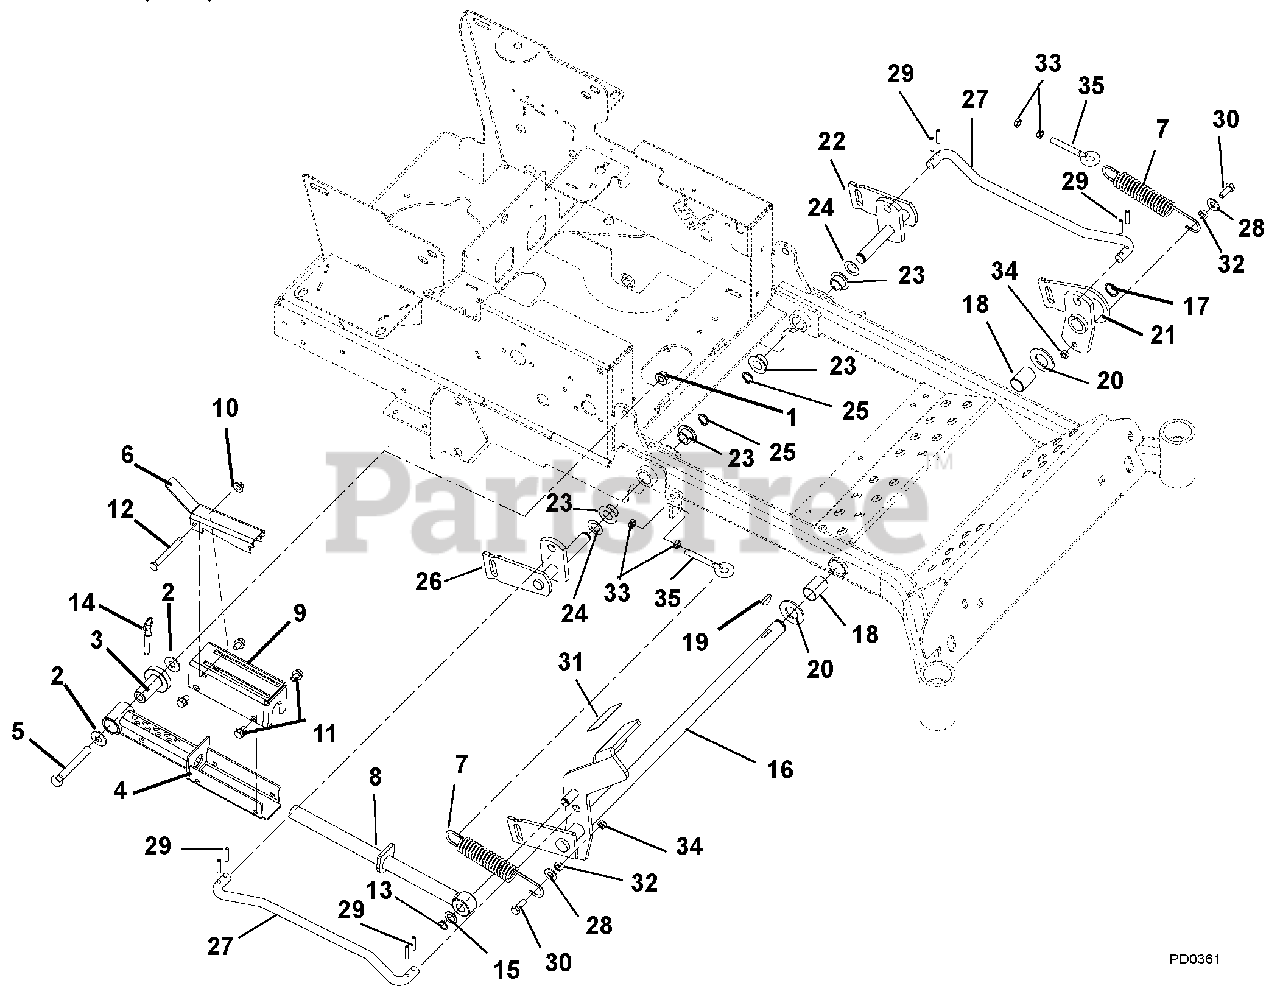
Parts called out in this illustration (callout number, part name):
1	Nut, Locking Top Flange .50-13
2	Washer, Flat Steel .531 x 1.25 x .10
3	Bearing, Pedestal
4	Weldment, Mechanical Lift
5	Bolt, Hex .50-13 x 3.75 Grade 5
6	Lock-Up, Mechanical Lift
7	Spring, Tension .162 x 1.25 x 8.25 Weldment 25
8	Weldment, Mechanical Lift Shaft
9	Weldment, Mechanical Lift Cover
10	Nut, Nyloc Flange 3/8-16
11	Screw, Tapping .38-16 x .50 Hex Washer Head
12	Bolt, Hex .38-16 x 3.25 Grade 5
13	Ring, Retaining External .625 x .050
14	Pin, Spring Ball .375 O.D. x 1.50
15	Washer, Flat Steel .630 x 1.005 x .062
16	Weldment, Foot Operated Deck Lift
17	Ring, Retaining External 1.00 x .078
18	Bushing 1.00 ID x 1.125 OD x 1.50
19	Key, Woodruff .25 x 1.00
20	Washer, Flat Steel 1.062 x 2.0 x .134
21	Weldment, Left Hand Mower Lift Arm
22	Weldment, Left Hand Rear Mower Lift Arm
23	Bushing, Flange Nylon .762 x 1.0 x .580 x 1.48
24	Washer, Hardened Steel .758 x 1.23 x .031
25	Ring, Retaining External .689 x .077
26	Weldment, Right Hand Rear Mower Lift Arm
27	Rod, Lift Assist
28	Washer, Flat Steel .438 x 1.00 x .083
29	Pin, Roll .25 x 1.25 Stainless Steel
30	Bolt, Hex .38-16 x 1.00 Grade 5
31	Grip, Pedal
32	Bushing, Sleeve .377 x .624 x .235
33	Nut, Hex-Jam .375-16
34	Nut, Locking-Jam-Center .375-16
35	Bolt, Eye .375-16 x 2.50
